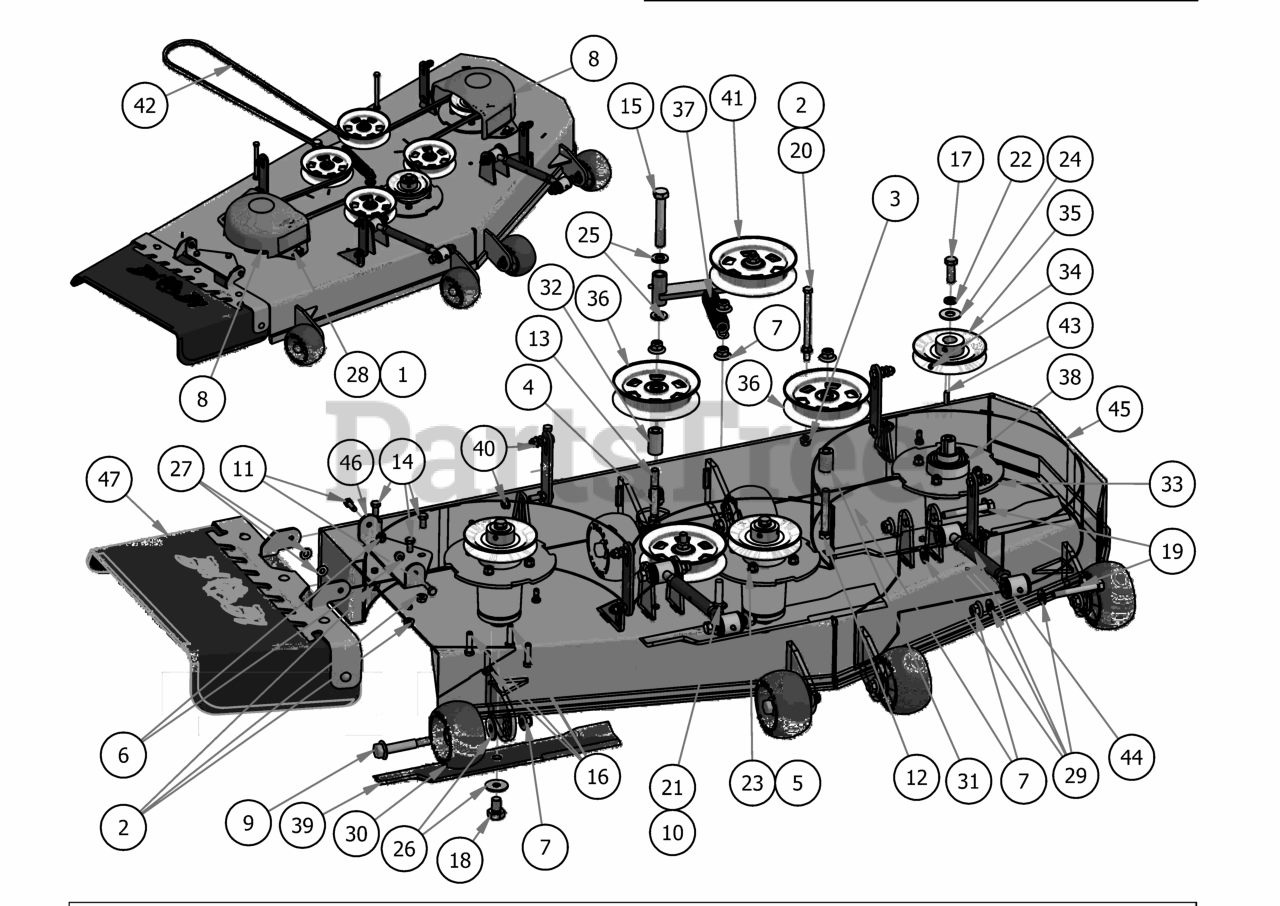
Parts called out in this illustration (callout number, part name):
1	Acorn nut-pulley Cover
2	3/8" Flange Nut
3	3/8" Nylock Flange Nut
4	5/8-11 Nylon Insert Jam Half Nut
5	3/8" Hex Nut
6	5/16" Nylon Flange Nut
7	1/2-13 Nylon Flange Nut
8	Pulley Cover
9	Deck Wheel Bolt
10	1/2 x 2" Carriage Bolt
11	5/16-18 x 1 GR 5 Hex Bolt Zinc
12	1/2 x 3 1/2 Flange Bolt Grade 8
13	1/2" x 4" Bolt (Grade 8)
14	3/8" x 3/4" Hex Bolt
15	5/8" x 4" Hex Bolt
16	3/8 x 1.5" Bolt
17	1/2"-20 x 1 1/2 - Grade 5 Fine Thread Bolt
18	5/8" x 1 1/2" Grade 8 Hex Bolt (Fine)
19	1/2-13 x 3 1/2 GR 5 Hex Bolt
20	3/8-16 x 5 1/2 Hex Bolt
21	.517 Square Hole Round Washer
22	1/2" Lock Washer
23	3/8" Lock Washer
24	5/8'' Flat Washer
25	.630 ID Plastic Washer
26	1/2" Belleville Washer
27	.360 ID Plastic Washer
28	.360 ID Plastic Washer-Black
29	.505 Nylon Spacer
30	Deck Wheel
31	.502 ID X .750 OD X 1.500 Long Spacer
32	1 3/4" Pulley Spacer
33	Deck Spindle Support Plate
34	5/16 Set Screw
35	5.25" Deck Spindle Pulley
36	5-3/4 Idler Pulley
37	Deck Idler Spring
38	Spindle Assembly
39	54" Deck Fusion Blade For Outlaw
40	Deck Hanger Assembly
41	2017 54"/48" Deck Idler Assembly
42	B155.75 Deck Belt
43	1/4" x 1" Key
44	2018 Maverick Turnbuckle (Top Link)
45	54 ZT Welded Deck
46	Discharge Chute Hanger (deck mounted)
47	Discharge Chute Assembly
